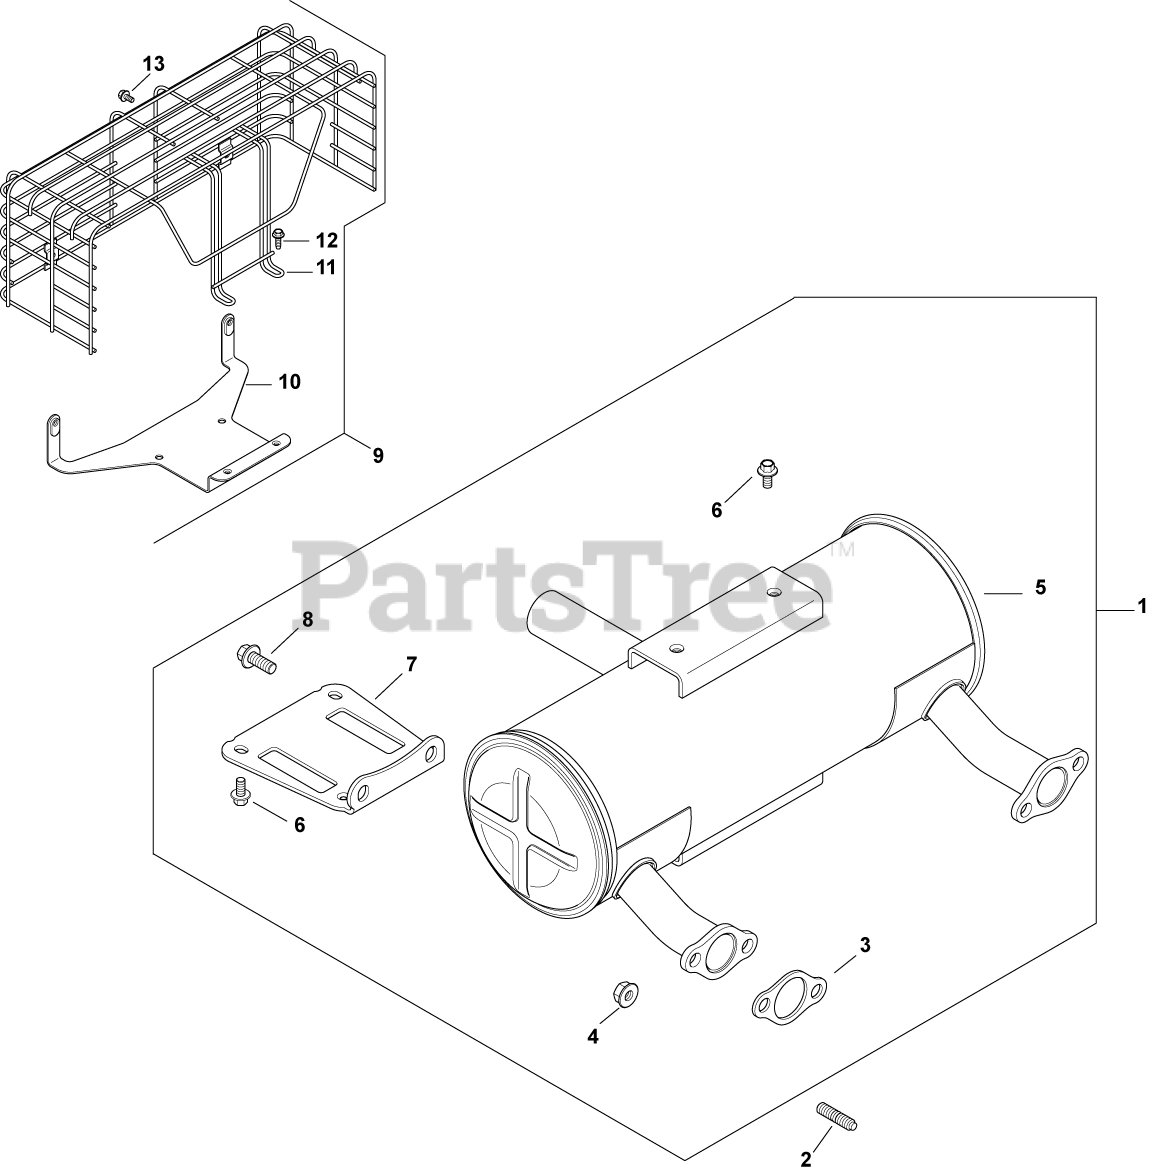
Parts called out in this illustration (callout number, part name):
1	KIT, MUFFLER
2	STUD, EXHAUST-USE 25 072 24-S
3	GASKET, EXHAUST
4	NUT, FLG M8X1.25
5	MUFFLER, CANISTER-STRT OUTLET - USE 24 068 129-S
6	SCREW, FLG M6X1.0X12
7	BRACKET, MUFFLER
8	SCREW, FLG M8X1.25X20
9	KIT, MUFFLER GUARD
10	BRACKET, EXHAUST GUARD
11	GUARD, MUFFLER
12	SCREW,FLG THD FRM M5X0.8X16-(#25086398S)
13	SCREW, HVY FLG M5X.8X10
